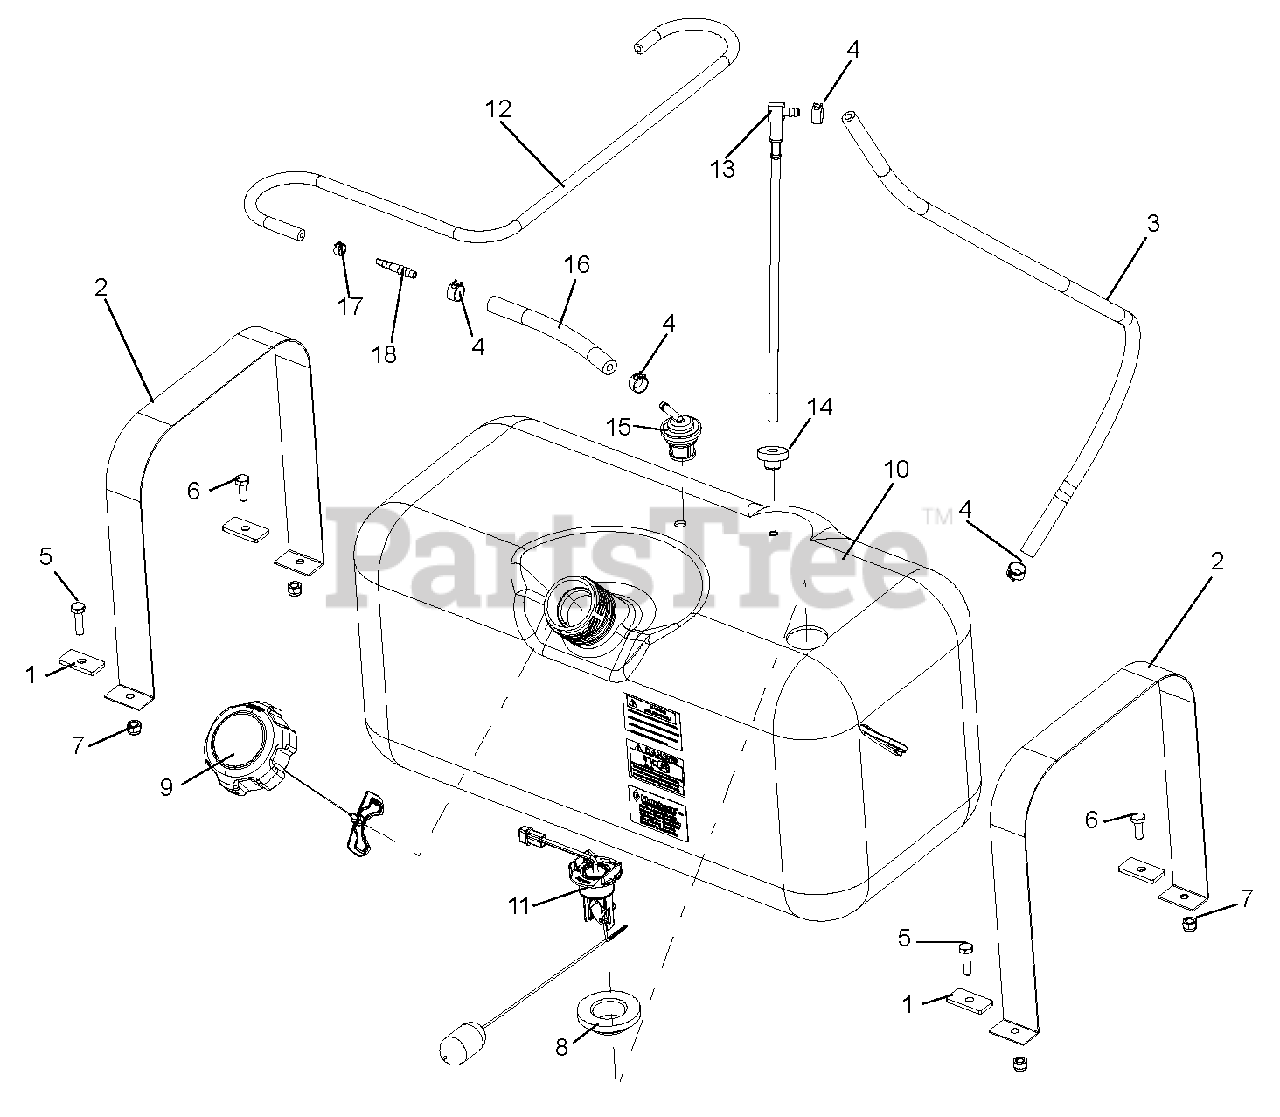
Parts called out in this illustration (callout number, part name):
1	GAS TANK MOUNT SPACER
2	GAS TANK STRAP, WIDE
3	FUEL LINE 10" ST MODEL
4	CLAMP, FUEL LINE, 1/4"
5	BOLT, HEX .25-20 X .75 GR5 YWZC
6	BOLT, HEX .25-20 X 1.00 GR5 YWZC
7	NUT, HEX NYLOCK .25-20 YWZC
8	GROMMET, FUEL SENDER
9	CAP, 2.25" ONE-WAY VENT FUEL
10	FUEL TANK, EPA
11	SENDER, FUEL LEVEL
12	HOSE, .188 LOW PERM 34"
13	FUEL, TANK PICK-UP LINE
14	GROMMET, DAPCO VITON #12240
15	IN-LINE CHECK VALVE, GROMMET FUEL TANK VENT
16	HOSE, .25 LOW-PERM BULK GAS, 6"
17	CLAMP, FUEL LINE, 3/16"
18	ADAPTOR, HOSE 3/16" TO 1/4"
